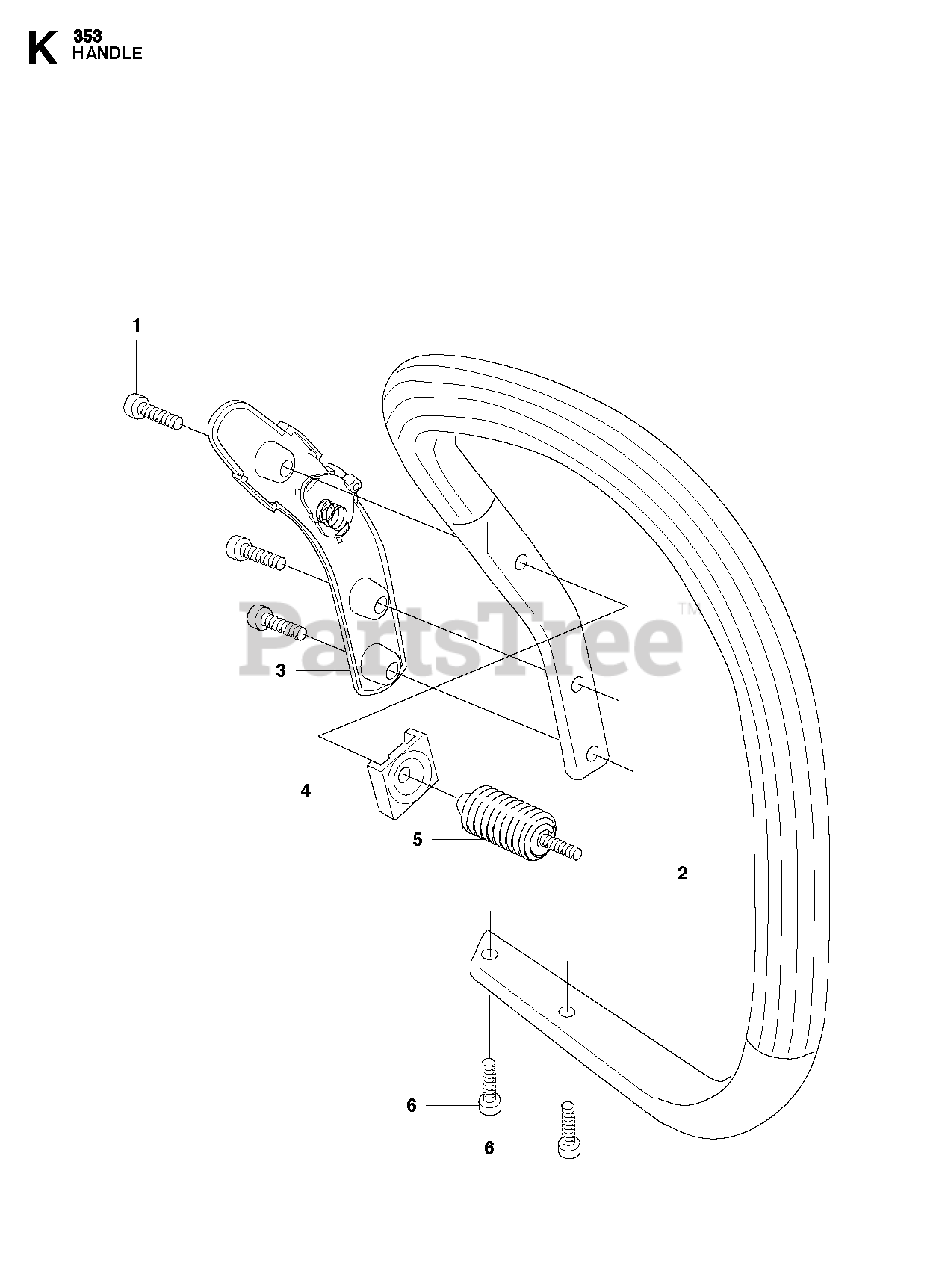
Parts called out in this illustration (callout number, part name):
2	FRONT HANDLE
3	SWITCH
6	SCREW IHSCFT
